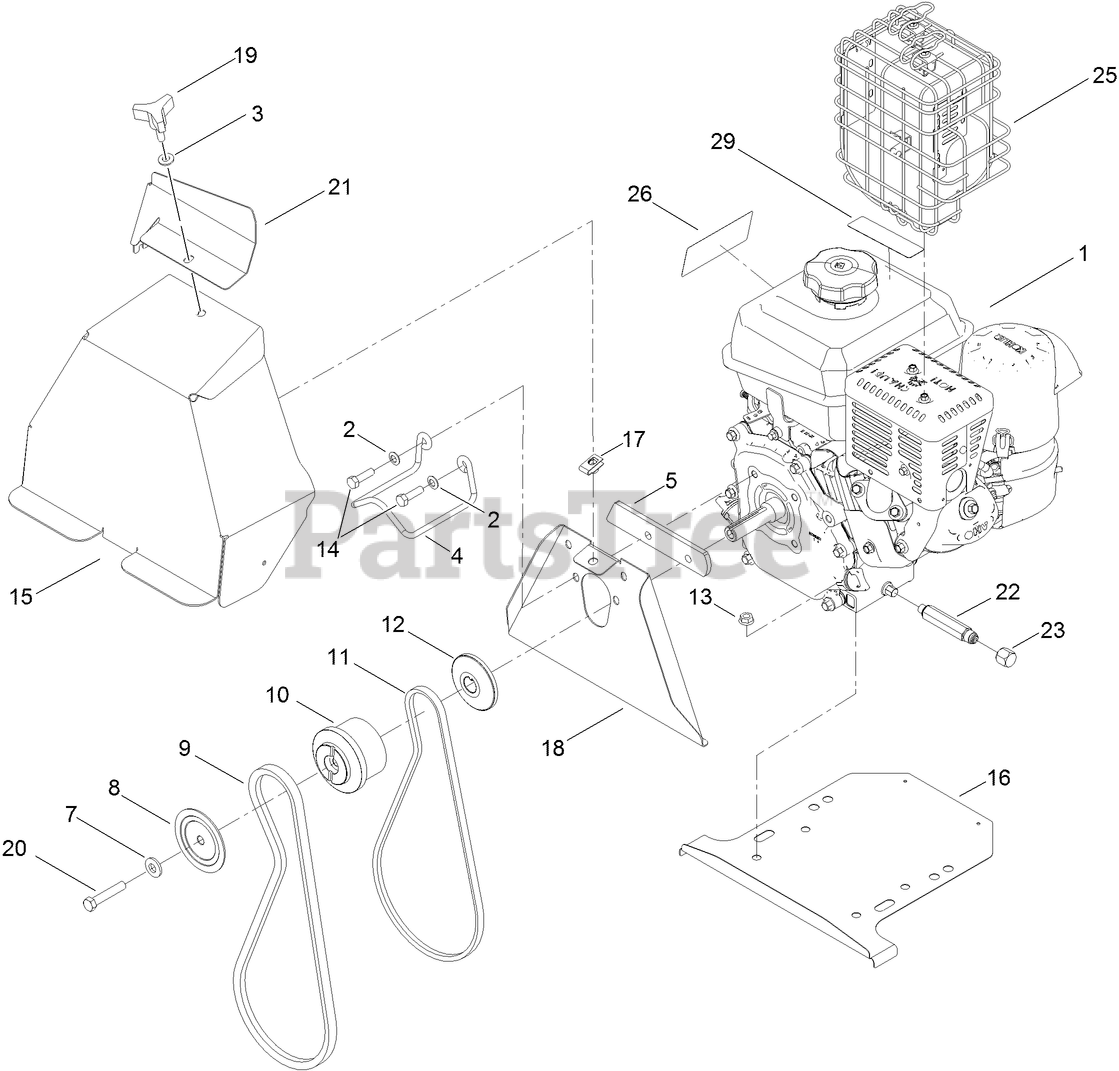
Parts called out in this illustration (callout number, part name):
2	WASHER-BELLEVILLE
3	WASHER-SPRING
4	GUIDE-BELT
5	SPACER-COVER, BELT
7	WASHER-BELLEVILLE
8	SHEAVE-HALF, IMPELLER
9	Belt-Blower
10	PULLEY-ENGINE, CENTER
11	V BELT-TRACTION
12	SHEAVE-HALF, TRACTION
13	NUT-HF
14	SCREW-HH
15	COVER-BELT
16	SHIELD-DRIVE
17	NUT-U
18	COVER-BELT, BACK
20	SCREW-HH
21	SHIELD-ICE
22	ADAPTER
25	GUARD-MUFFLER
26	DECAL-ENGINE FUEL
29	DECAL-ARRESTER, SPARK
